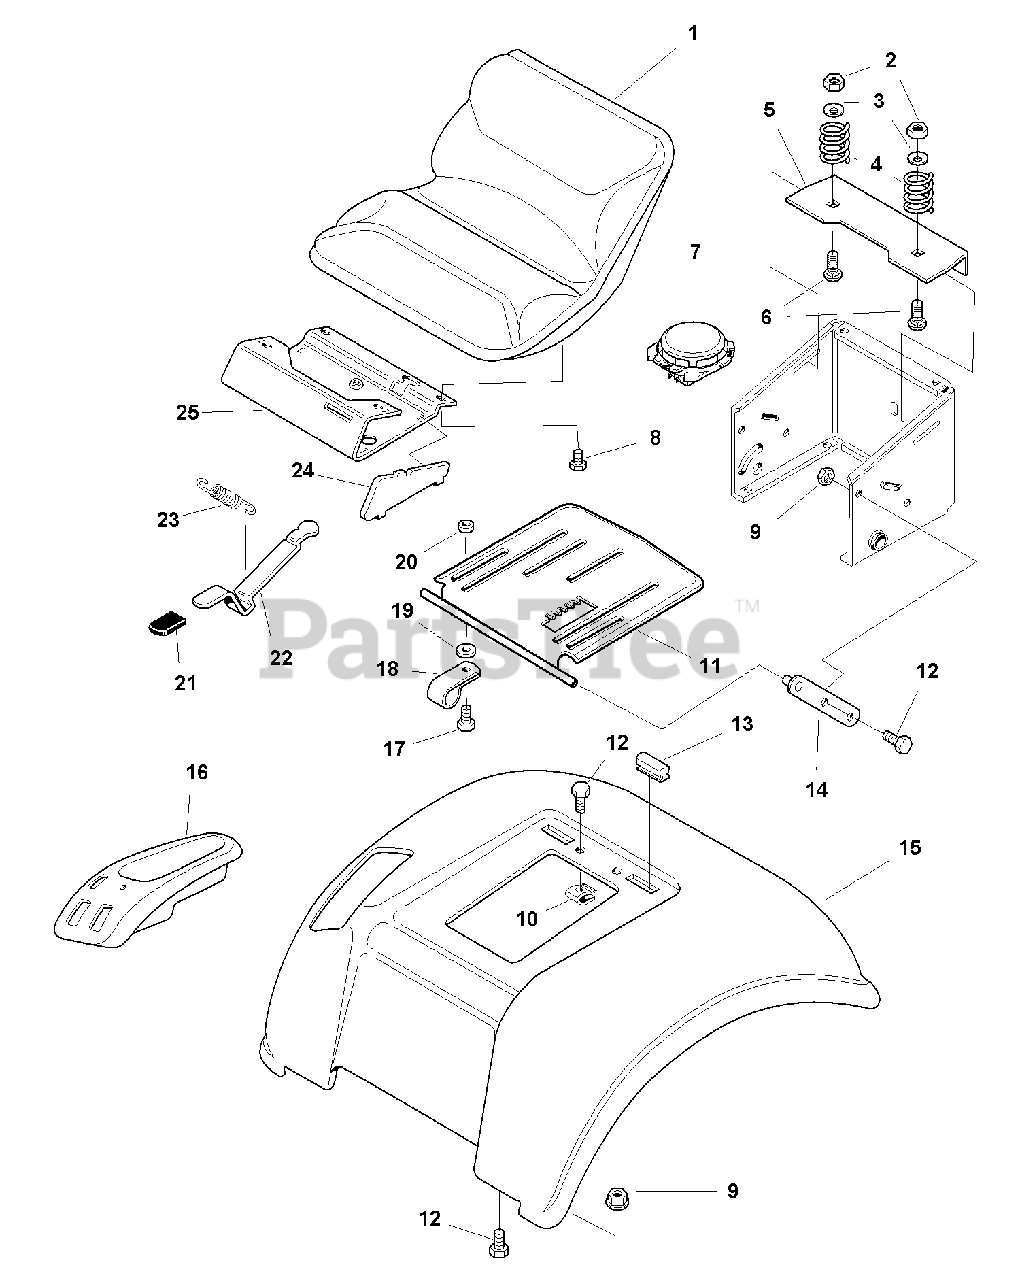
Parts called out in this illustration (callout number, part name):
1	* SEAT ASSEMBLY
2	NUT, Hex Nylon Lock, 5/16-18
3	WASHER,5/16
4	SPRING, Seat
5	PLATE, Spring Support
6	CARRIAGE BOLT, 5/16-18 x 3/4
7	SWITCH, Seat, Used with Seat P/N 1721702
8	CAPSCREW, Hex Head Whiz Lock, 5/16-18 x 1/2
9	NUT, Hex Flange Whiz-Lock, 5/16-18
10	SPEED NUT, Tinnerman Lug Type, 5/16-18
12	CAPSCREW, Hex Head Whiz Lock, 5/16-18 x 3/4
13	STOP, Rubber Seat
14	BAR, Seat Pivot
15	SEAT DECK, Orange
15	SEAT DECK, Red
16	CONTROL POD, Hydro
17	CAPSCREW, Taptite Hex Washer Head, 5/16-18 x 5/8
18	CLAMP, Wire (Middle Bolt Only)
19	WASHER, 5/16
21	CAP, Seat Adjust
22	LEVER, Seat Latch
23	SPRING, Extension
24	SIDE PANEL, Seat Slide
25	SLIDE, Seat
